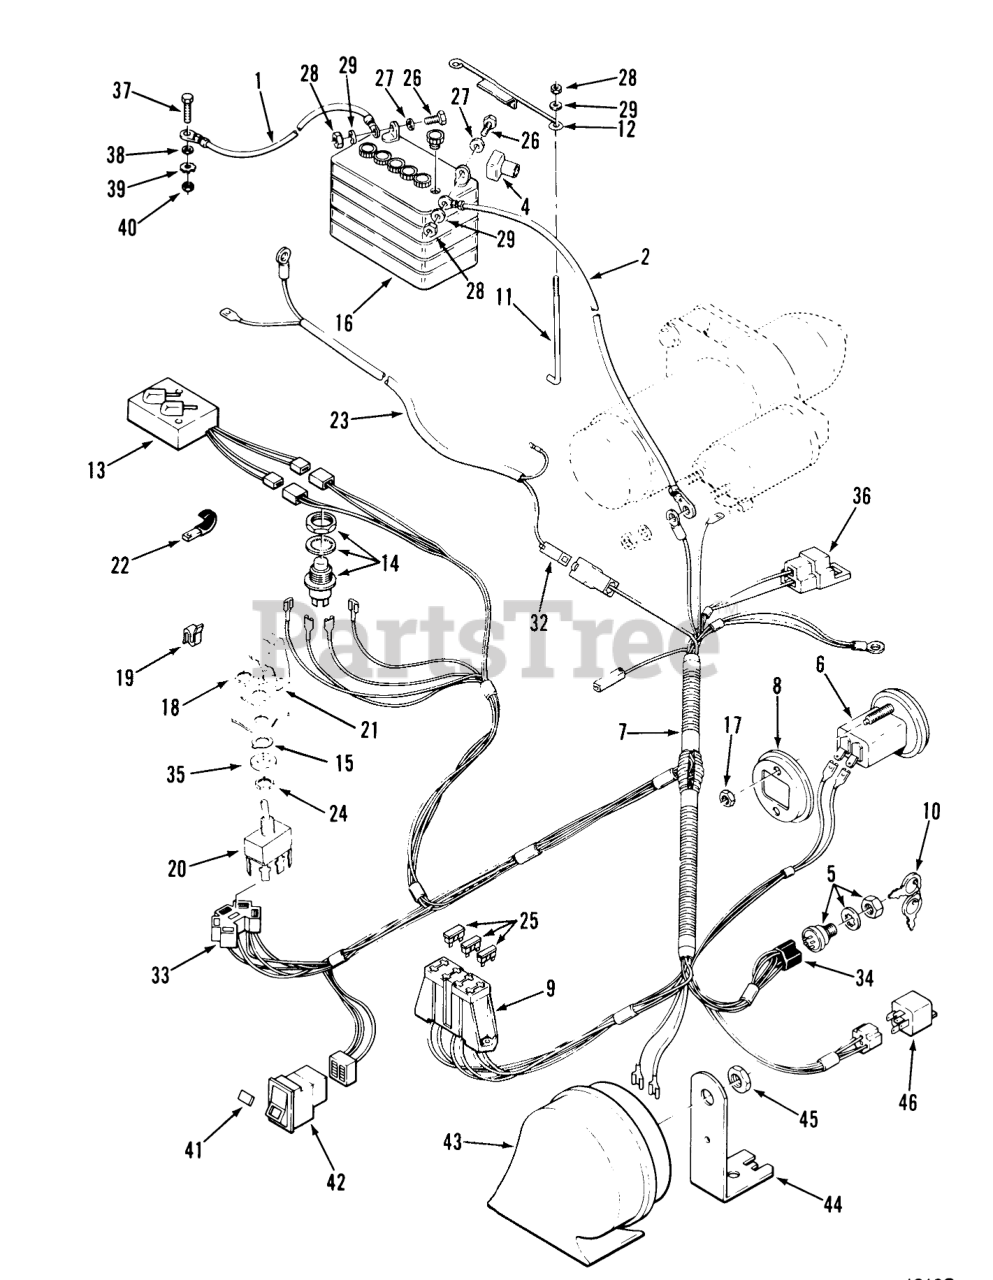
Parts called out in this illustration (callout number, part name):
1	WIRE -BLACK
2	ASS'Y-WIRE BATTERY
4	Boot
5	Switch-Ignition (Incl. #101884 Nut)
6	Hourmeter (Incl. Item # 8)
7	MAIN-HARNESS & DIAG
8	CLAMP-HOUR METER
9	AUTO-FUSEBLOCK TERM
10	KEY-IGNITION
11	HOOK-BATTERY RETAIN
12	HOLDDOWN-BATTERY
13	SWITCH-ASS'Y NEUTRAL
14	SWITCH-PLUNGER
15	TAB-WASHER
16	Battery
17	NUT-HEX
19	CLIP-CABLE
20	SWITCH-ELECT CLUTCH
21	COVER-PTO SWITCH
22	CLIP
23	ENG WIRING HARNESS
24	NUT-HEX, SPECIAL
25	FUSE-BLADE, 15 AMP
26	SCREW-HH
27	WASHER-FLAT
28	NUT-WING
29	WASHER-LOCK
32	MALE CONNECTOR
33	CONNECTOR 5 WAY
34	CONNECTOR-5 WAY-SERV
35	WASHER
36	CONNECTOR BODY
37	SCREW-HH
38	WASHER-FLAT
39	WASHER-LOCK
40	NUT-HEX
41	LENS-ENG TEMP
42	SWITCH-TEST
44	BRACKET-HORN
45	LOCKNUT
46	RELAY
